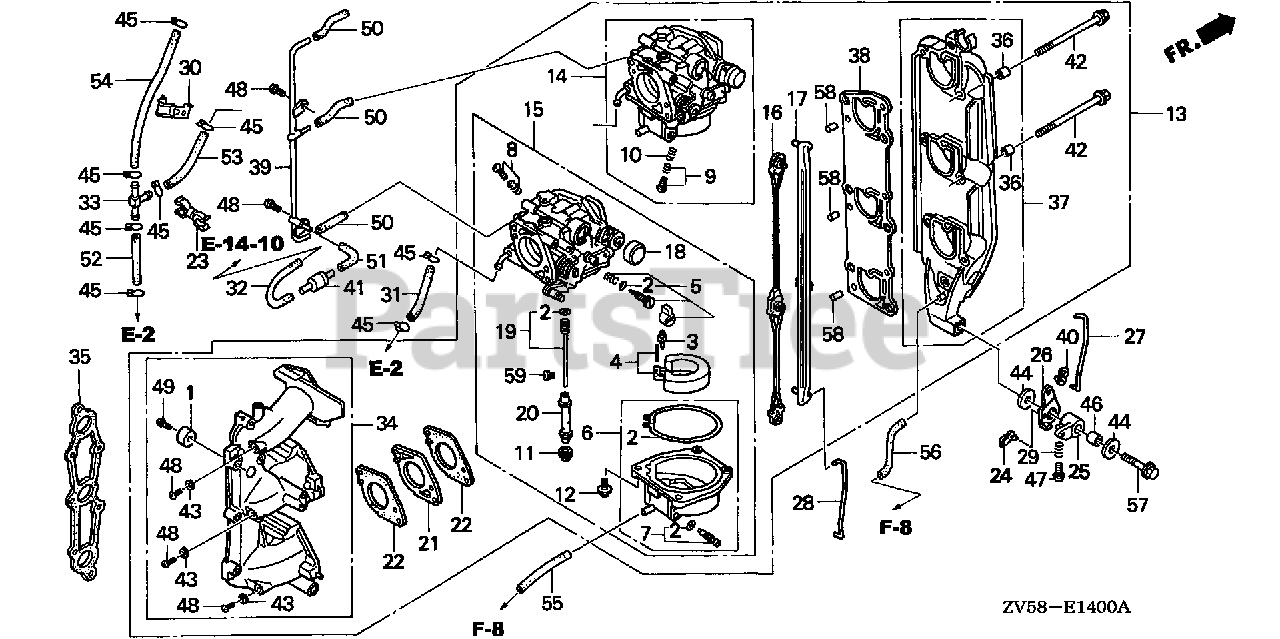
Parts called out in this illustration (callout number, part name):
1	METAL, ANODE
2	GASKET SET
3	VALVE SET, FLOAT
4	FLOAT SET
5	SCREW SET (CARBURETOR NO.)
6	CHAMBER SET, FLOAT
7	SCREW SET, DRAIN (CARBURETOR NO.)
10	SPRING, COMPRESSION COIL
11	SCREW, PLUG
12	SCREW-WASHER
13	CARBURETOR ASSY. (BG30C A) *NH8* (DARK GRAY)
13	CARBURETOR ASSY. (BG30C B) *NH8* (DARK GRAY)
14	CARBURETOR ASSY. (#1/#2) (CARBURETOR NO.)
15	CARBURETOR ASSY. (#3) (CARBURETOR NO.)
16	LEVER, LINK
17	LINE, CHOKE
18	CAP, CHOKE LEVER DUST
19	JET SET (#102)
20	NOZZLE, MAIN
21	INSULATOR, CARBURETOR
22	GASKET, CARBURETOR
23	CLAMP, FUEL TUBE (A)
24	JOINT, ROD
25	ARM A, CHOKE
26	ARM B, CHOKE
27	ROD, CHOKE
28	ROD, CHOKE KNOB
29	SPRING, CHOKE ARM ADJUSTING
30	CLAMP, FUEL TUBE
31	TUBE C, FUEL
32	TUBE D, FUEL
33	PIPE, THREE WAY JOINT
34	MANIFOLD, IN. *NH8* (DARK GRAY)
35	GASKET, IN. MANIFOLD
36	COLLAR, DISTANCE (6.5X11X7.5)
37	PLATE, MUFFLER
38	GASKET, MUFFLER PLATE (CARBURETOR NO.)
39	PIPE, INSTALL
40	BUSH, LINKAGE
41	VALVE, DASHPOT CHECK
42	BOLT, FLANGE (6X97)
43	WASHER, SEALING (5MM)
44	WASHER, PLAIN (6MM)
45	CLIP, TUBE (B10)
46	COLLAR, DISTANCE (6.5X10.5X16)
47	SCREW, PAN (4X16)
48	SCREW, PAN (5X10)
49	SCREW, PAN (6X18)
50	BULK HOSE, FUEL (3.5X3000) (3.5X120)
51	BULK HOSE, FUEL (3.5X3000) (3.5X120)
52	BULK HOSE, FUEL (5.5X3000) (Honda Code 5338587). (5.5X150)
53	BULK HOSE, FUEL (5.5X3000) (Honda Code 5338587). (5.5X150)
54	BULK HOSE, FUEL (5.5X3000) (Honda Code 5338587). (5.5X150)
55	BULK HOSE, VINYL (3.5X6.5X8000) (9500(95003-05001-60M) (CARBURETOR NO.)
56	BULK HOSE, VINYL (3.5X6.5X8000) (9500(95003-05001-60M) (CARBURETOR NO.)
57	BOLT, FLANGE (6X28)
58	ROLLER (6X15)
59	JET, MAIN (#88)
59	JET, MAIN (#90) (NOT AVAILABLE)
59	JET, MAIN (#92)
